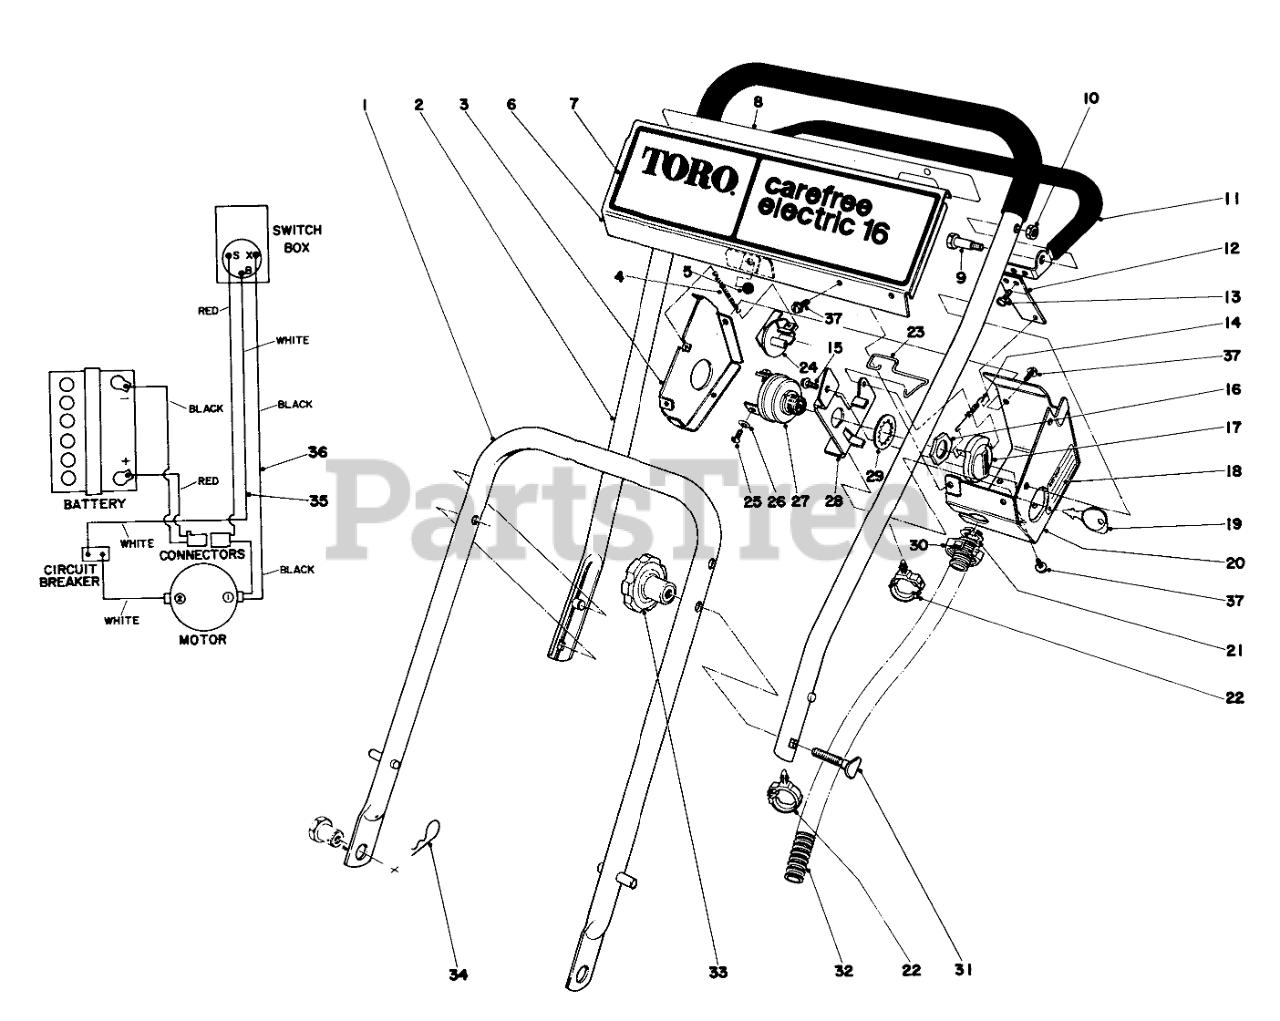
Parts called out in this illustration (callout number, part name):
1	Lower Handle
2	Handle Assembly Upper
3	Cover Plate
4	Spring Interlock Lever
5	Bumper
6	Control Panel
7	Decal Control Panel
8	Decal Safety Instructions
9	Screw
10	NUT-LOCK
11	Lever Dead Man
12	Lever Spring
13	SCREW-HWH
14	Spring Switch
15	SCREW-HWHTF
16	NUT-HH
17	Switch Actuator
18	Decal Key Position
19	Key
20	Switch Box
21	Nylinder
22	Clip Support
23	Wire Stop
24	Interlock Lever
25	Screw
26	WASHER-LOCK, INT
27	Switch
28	Mounting Plate Switch
29	WASHER-TOOTH, INTERNAL
30	FITTING-RING
31	SCREW-HANDLE
32	Cover Harness
34	PIN-COTTER, HAIR
35	Lead Wire
36	Harness-Main
37	10-16 X 3/8 THDG SCREW
